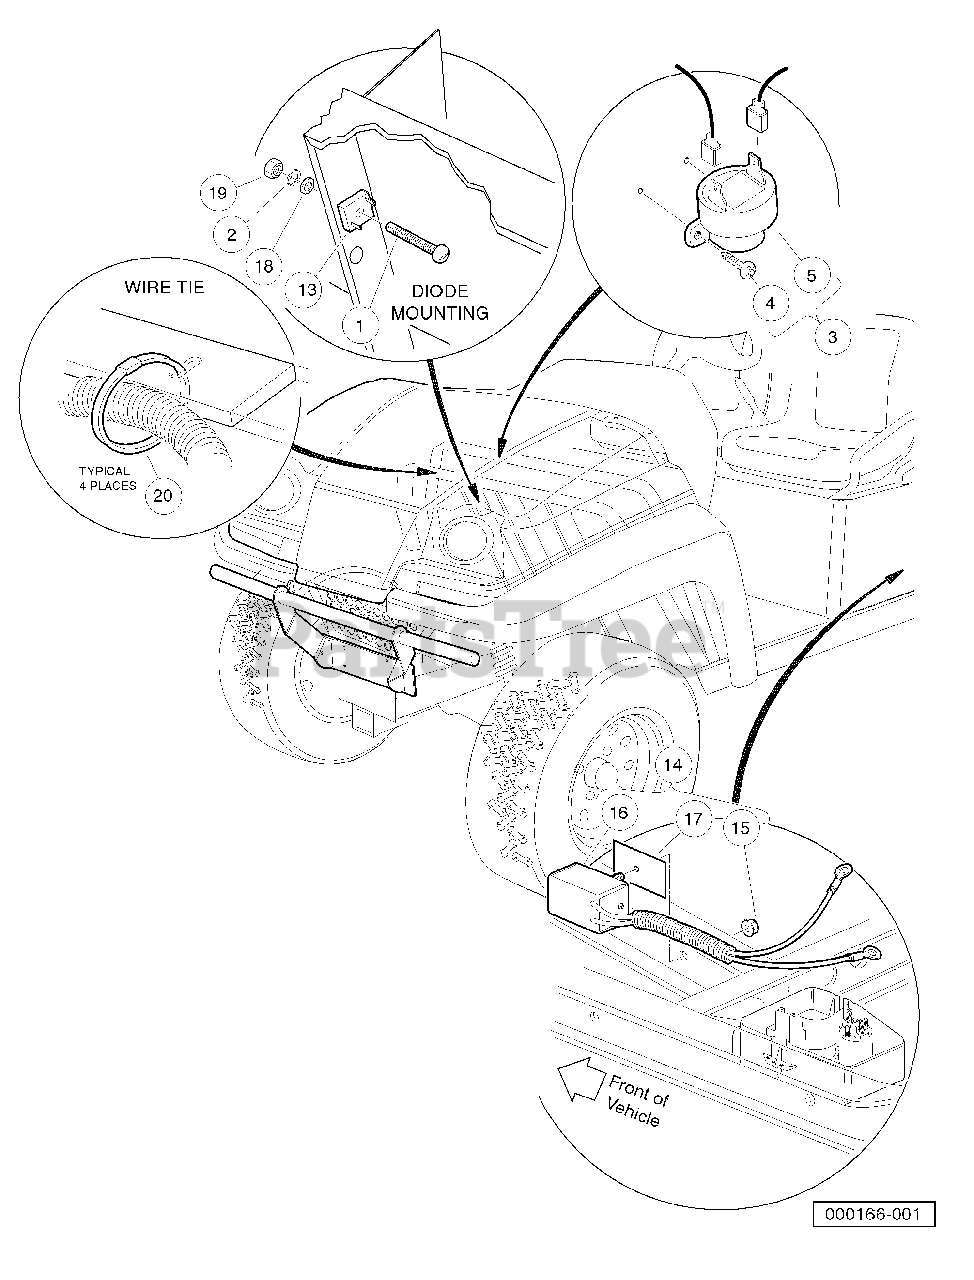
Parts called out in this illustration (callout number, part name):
1	Screw, #10-32 X 1.25 Rd Hd Mch
2	Washer, #10 Split Lock
3	Kit, Reverse Buzzer
4	Locknut, #6-32 Whiz
5	Washer, #4 Flat
6	Screw, #6-32 X 1/2 Hex Washer-Head
7	Screw, #4-24 X 0.33 Pan-Head Machine
8	Buzzer, Reverse
10	Screw, #4-40 X 0.75 Round-Head Machine
11	Nut, #4-40 Hex Machine
12	Lockwasher, #4 Helical Split
13	Limiter, Voltage
14	Kit, Diode
15	Locknut, 5/16-18 Hex Flange
16	Diode Assembly
17	Thermal Pad
18	Washer, #10 Type A Flat
19	Nut, #10-32 Hex
20	Tie Wrap, 11" Nylon
